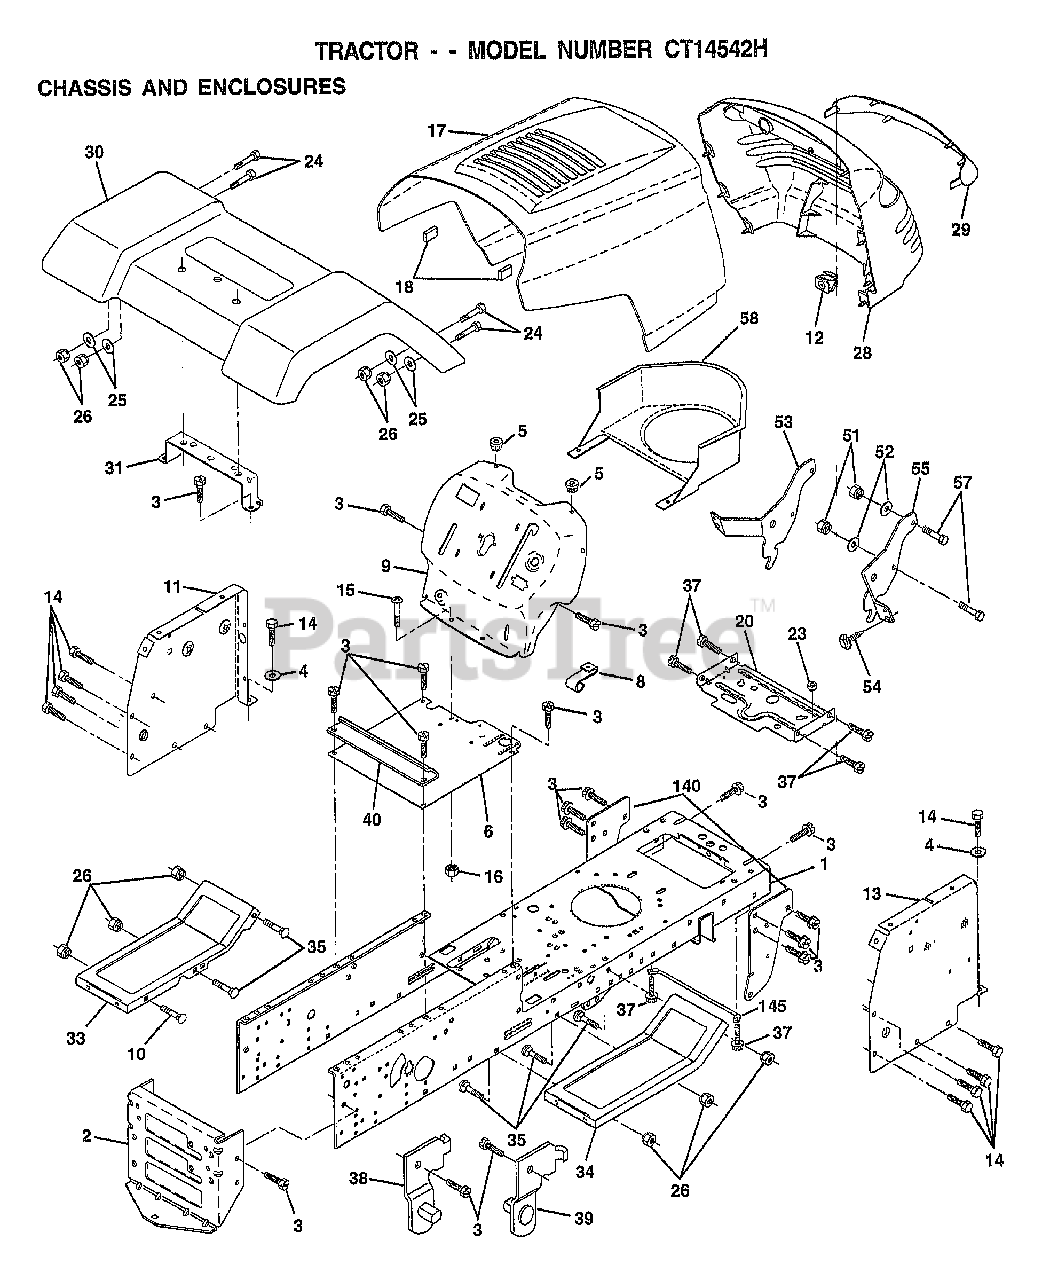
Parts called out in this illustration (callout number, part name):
1	CHASSIS.STAMPING
3	SCREW
4	WASHER
5	BUMPER-HOOD/DASH
6	SADDLE
8	CLIP.RETAINER
9	DASH SILKSCREEN
11	"PANEL-DASH,LH"
12	CLIP.TINNERMAN
13	PANEL.ASM.DASH.RH
14	SCREW LT
15	SCREW
17	HOOD.STEEL.ASSY
20	"PLATE-MTG,BATT/FU"
24	BOLT
25	WASHER
26	NUT
28	GRILLE-MS428
29	LENS.GRILLE.PRIVATE LABEL
30	FENDER.LTST.WLDMNT.W.SHIFT
31	BRACKET SUPT FEND
33	FOOTREST.LH.PERF.
34	FOOTREST.RH.PERF.
35	BOLT
37	SCREW LT
38	BRACKET ASM LH
39	BRACKET ASM RH
40	SPACER FENDER LT
51	NUT
52	WASHER
53	BRACKET.GRILLE.LH
54	SCREW.HEX.WS.HD
55	BRACKET.GRILLE.RH
58	DUCT.AIR.B&S.18HP
140	BRKT SUSPENSION
145	"ROD POVOT,CHASSIS"
